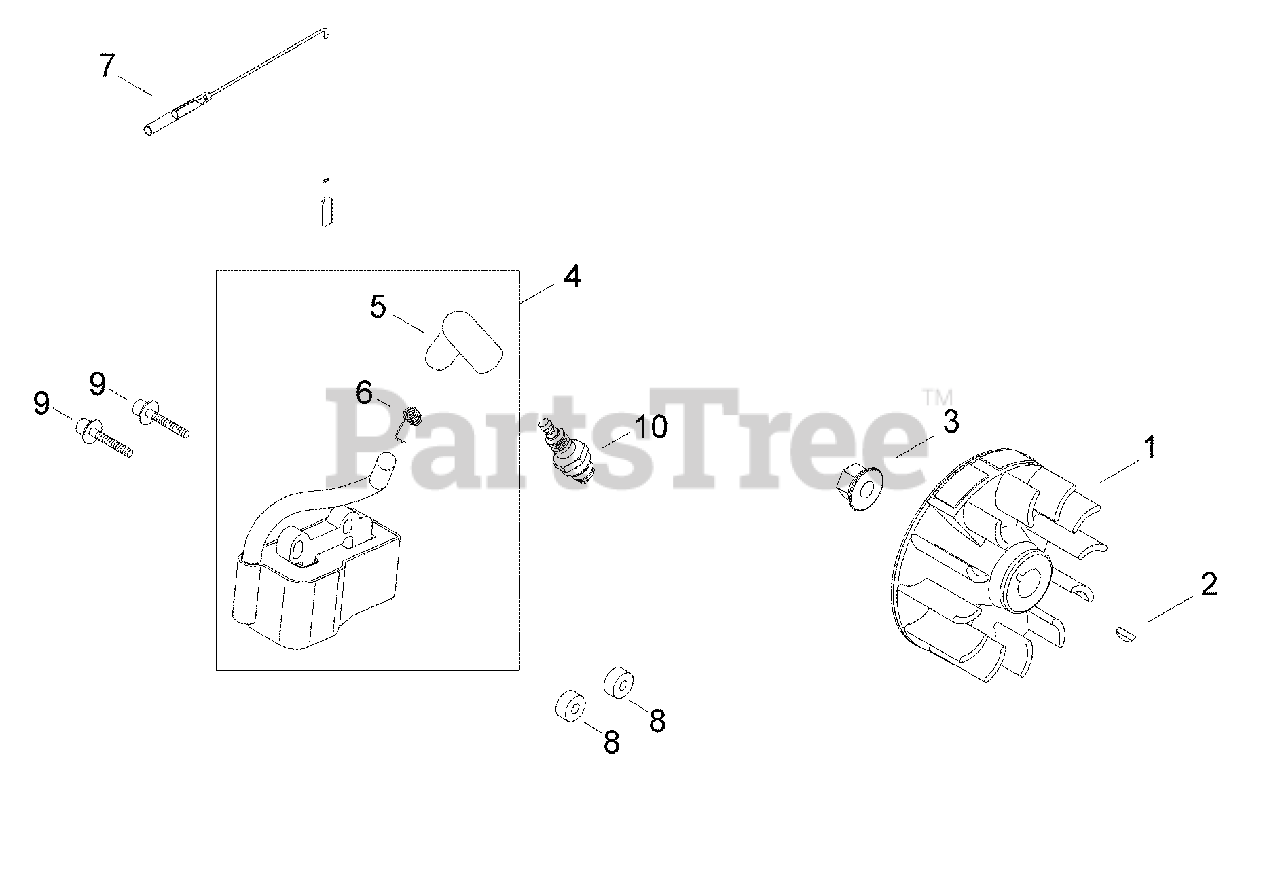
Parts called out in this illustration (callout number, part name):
1	FLYWHEEL
2	KEY - 3X10
3	NUT - 8
4	IGNITION COIL ASSY
5	CAP, SPARK PLUG
6	TERMINAL, SPARK PLUG CAP
7	LEAD - IGNITION
8	INSULATOR
9	SCREW - 4X26
10	SPARK PLUG -- CMR-5H
